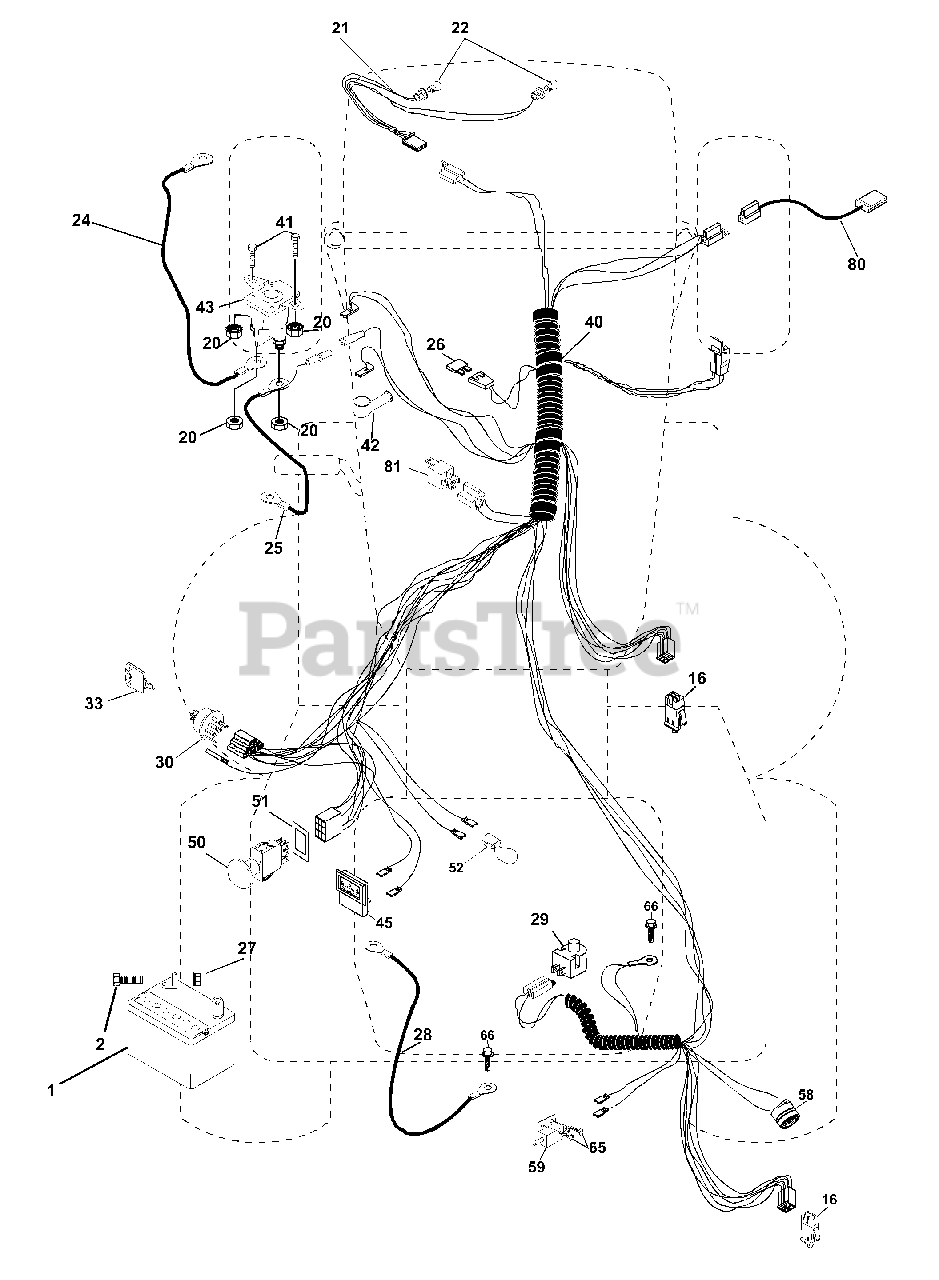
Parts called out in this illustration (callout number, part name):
1	Battery 12 Volt 25 Amp
2	Bolt Hex Hd 1/4-20unc X 3/4
16	Switch Interlock
21	Harness Asm Light W/4152J
22	Bulb Light #1156
24	Cable Starter 6 Ga 11" Red
25	Cable Battery CRD 56" Red
26	Fuse 15 Amp
27	Nut Keps Hex 1/4-20 Unc
28	Cable Ground
29	Switch Plunger OP Olive
30	Switch Ign
40	Harness Ign
41	Bolt Blk Fin Hex 1/4-20 Unc x 1/2
42	Cover Terminal Red
43	Solenoid
45	Ammeter Rectangular 15 Amp
50	Switch PTO 3PDT Blk Delta
51	Ring Retainer PTO
52	Protection Wire Loop
58	Buzzer CRD
59	Switch FBI CRD
65	Screw Slfts #10-16 x 1/2
66	Screw Thdrol 3/8-16 x 1/2
80	Harness Clutch Evx
81	Relay Asm.
